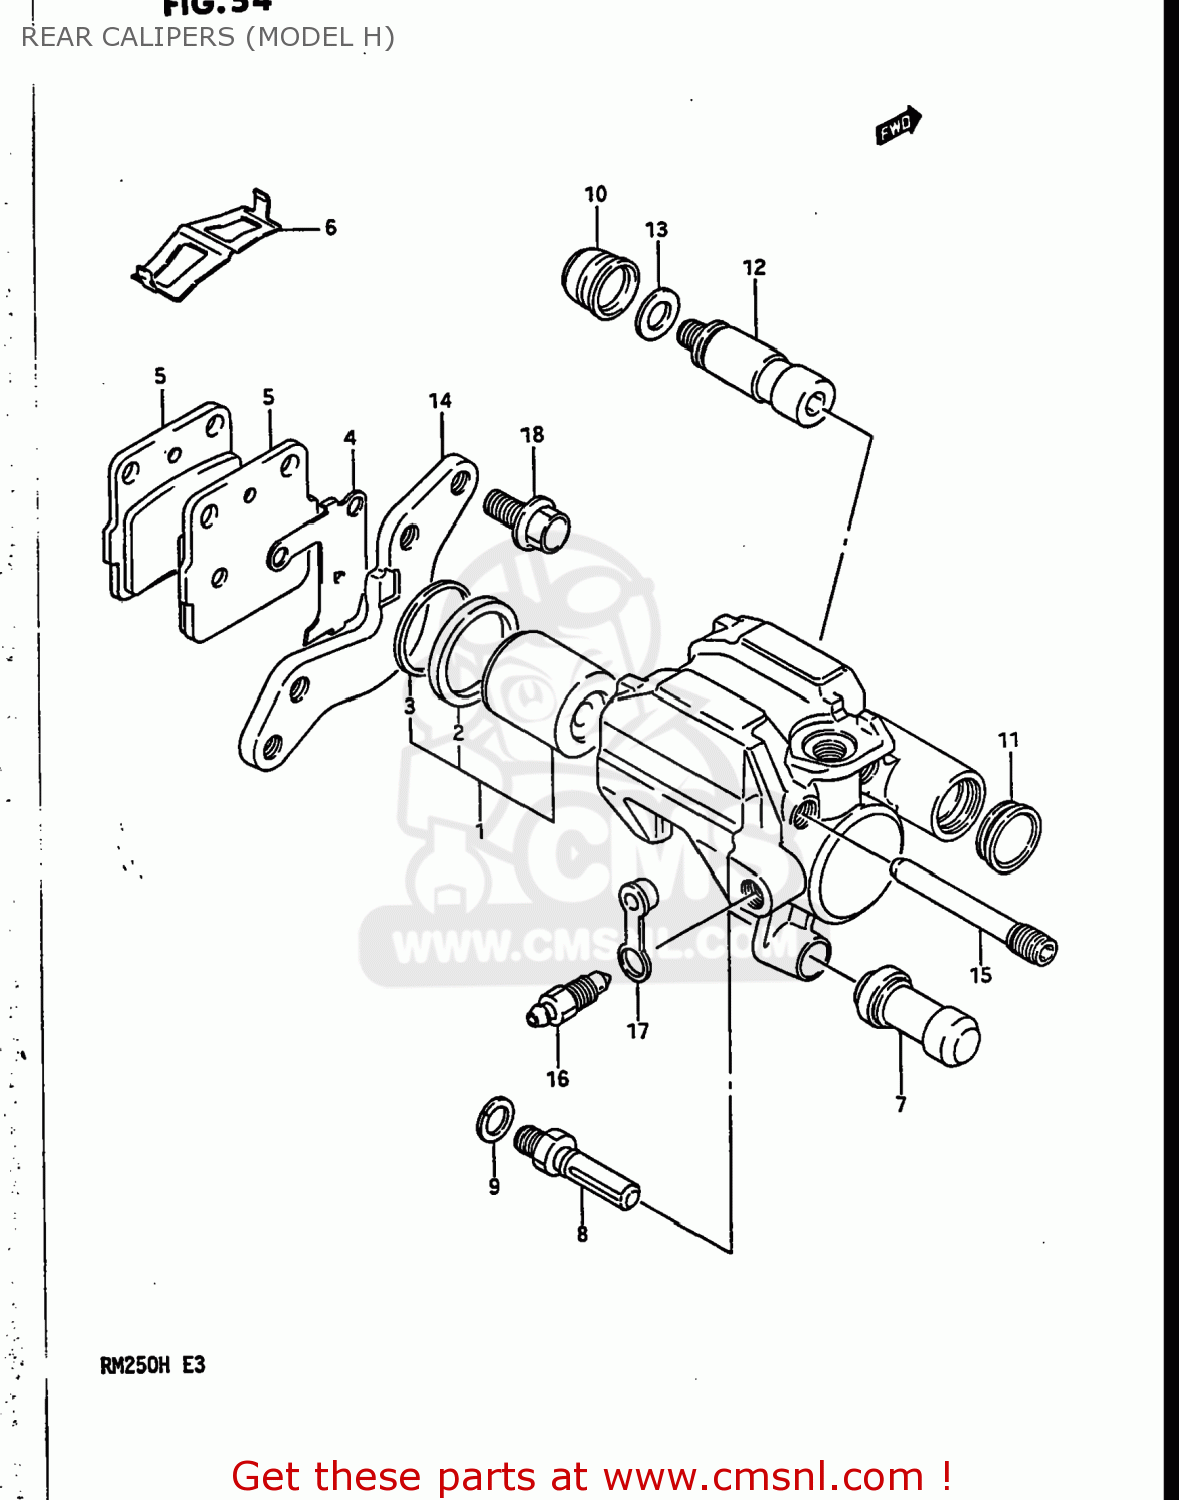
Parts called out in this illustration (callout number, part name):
1	PISTON SET
2	SEAL,PISTON
3	SEAL,DUST
4	SHIM
5	PAD
6	SPRING,PAD
7	BOOT
8	BOLT,PIN
9	WASHER,WAVE
10	BOOT,PIN
11	DUST SEAL
12	PIN,SLIDE
13	SPRING,FRICTION
14	BRACKET
15	PIN
16	BLEEDER
17	CAP,BLEEDER
18	BOLT(8X18)
